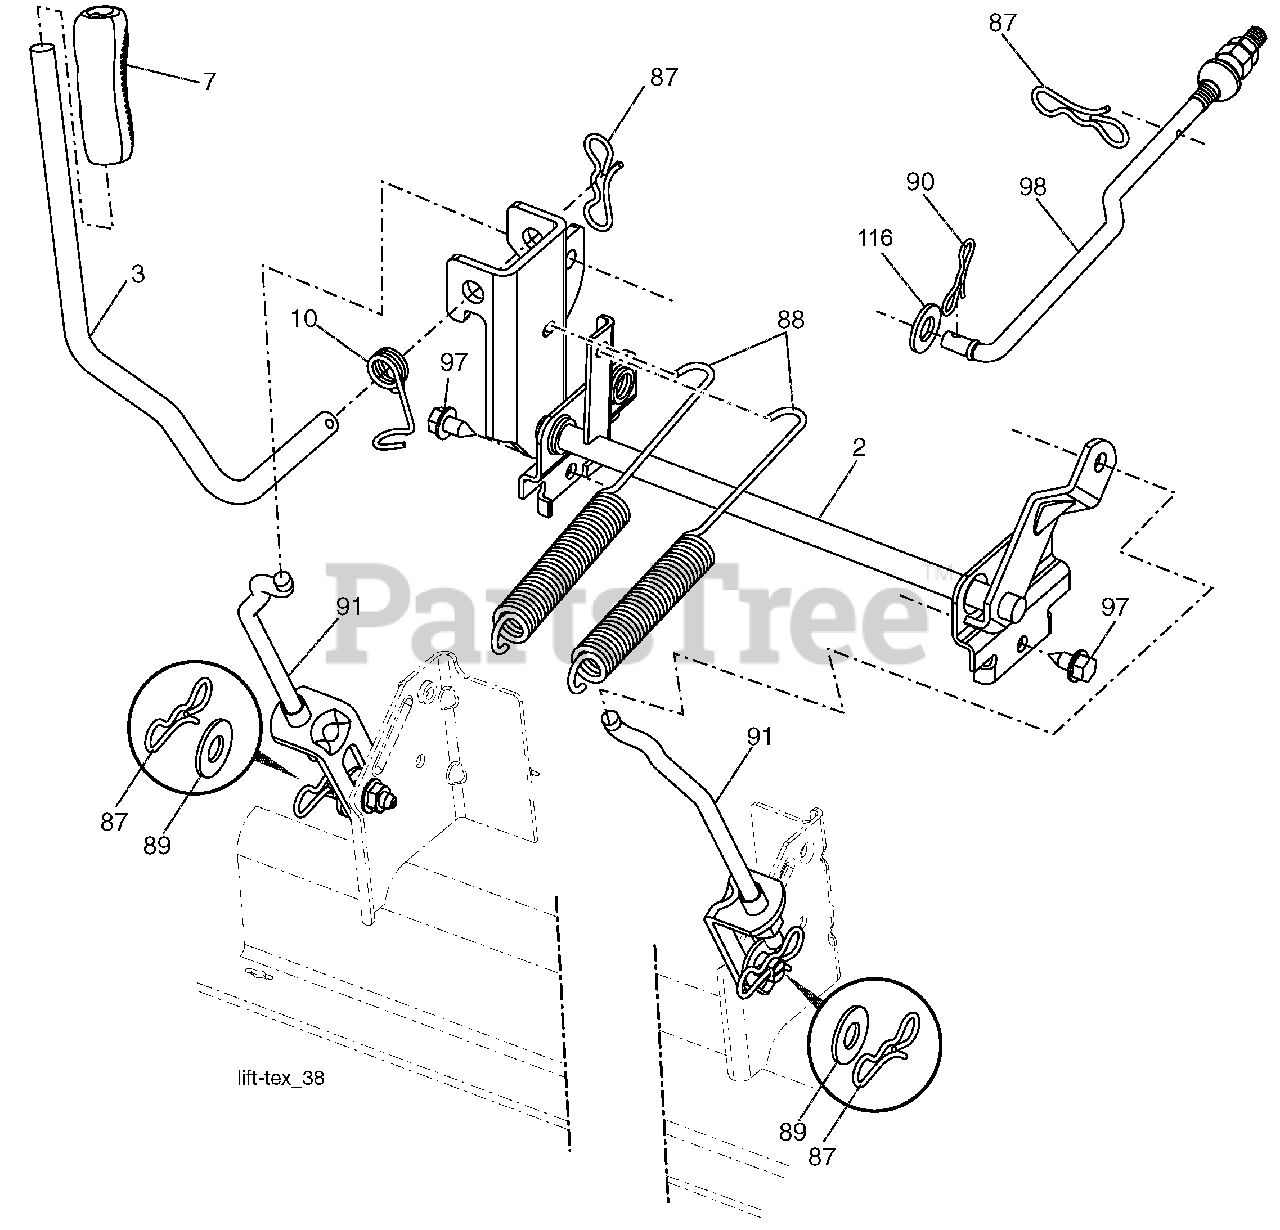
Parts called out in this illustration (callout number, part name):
2	SHAFT ASM.LIFT.CROSS.HD.
3	LEVER.LIFT.HANDLE.LT
7	GRIP LEVER 5625 LD BLACK 428
10	SPRING.TORSION.HANDLE.LIFT
87	PIN.COTTER.7/16.BOW TIE LOCK
88	SPRING.LIFT ASSIST
89	WASHER.CLEAR ZINC
90	PIN.COTTER.5/16.BOW TIE LOCK
91	LINK ASM.LIFT.LH.REAR
97	SCREW.HEXWSH THDR3/8-16X3/4.BL
98	LINK ASM.SUSP.FRONT.MWR.10.5
116	WASHER 15/32 X 15/16 X 16 GA.
